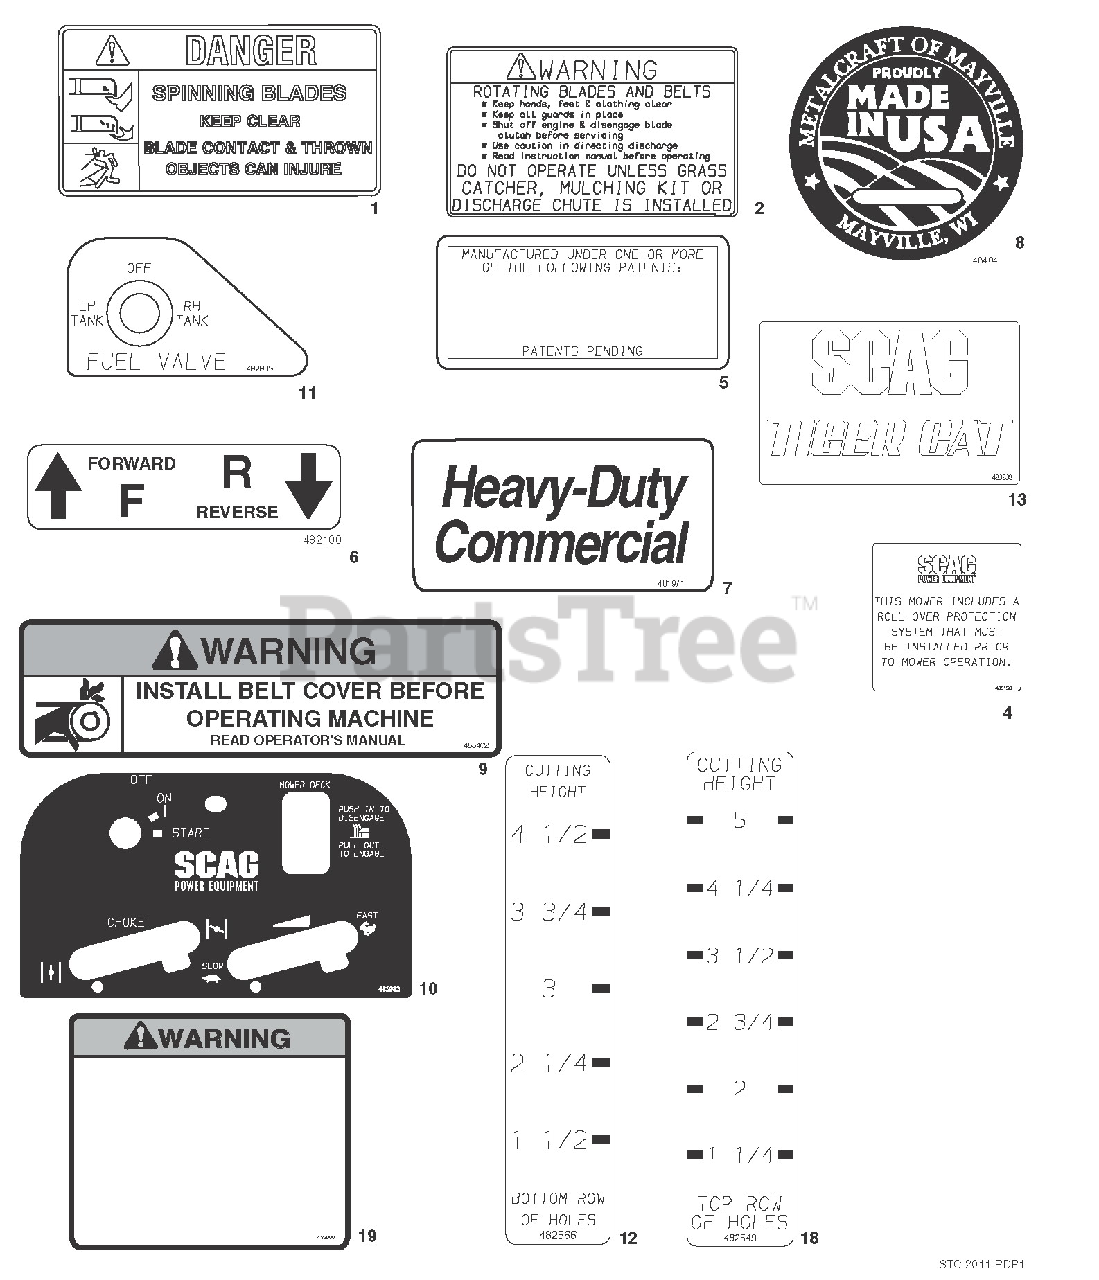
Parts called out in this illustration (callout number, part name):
1	Decal, Danger-Spinning Blades
2	Decal, Warning-Rotating Blades
4	Decal, ROPS
5	Decal, Patents
6	Decal, Traction Control
7	Decal, Heavy Duty Commercial
8	Decal, Metalcraft - Made in USA
9	Decal, Belt Cover
10	Decal, Instrument Panel
11	Decal, Fuel Valve Position
12	Decal, Cutting Height Bottom Row of Holes
13	Decal, Tiger Cat
18	Decal, Cutting Height Top Row of Holes
19	Decal, Warning Spark Arrestor
